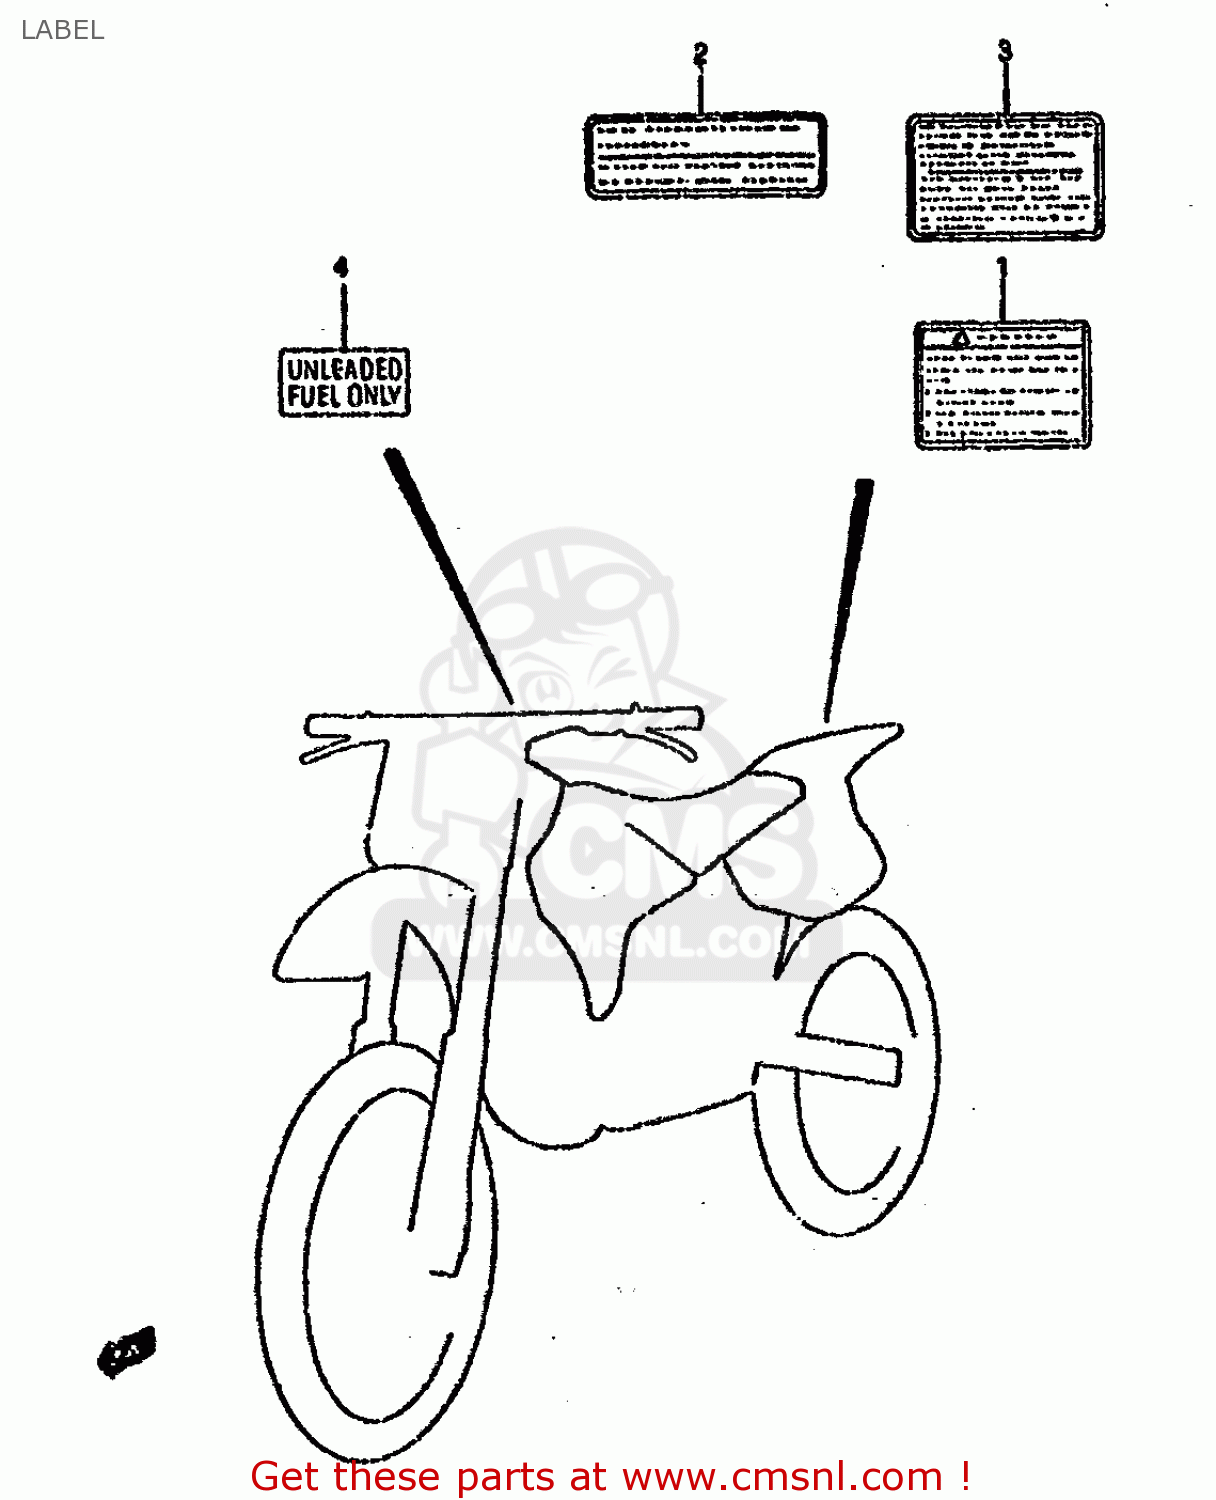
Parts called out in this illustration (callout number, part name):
1	LABEL
2	LABEL,WARNING NO.2
3	LABEL,WARNING
4	LABEL,UNLEADED FUEL
5	MANUAL,OWNER'S
